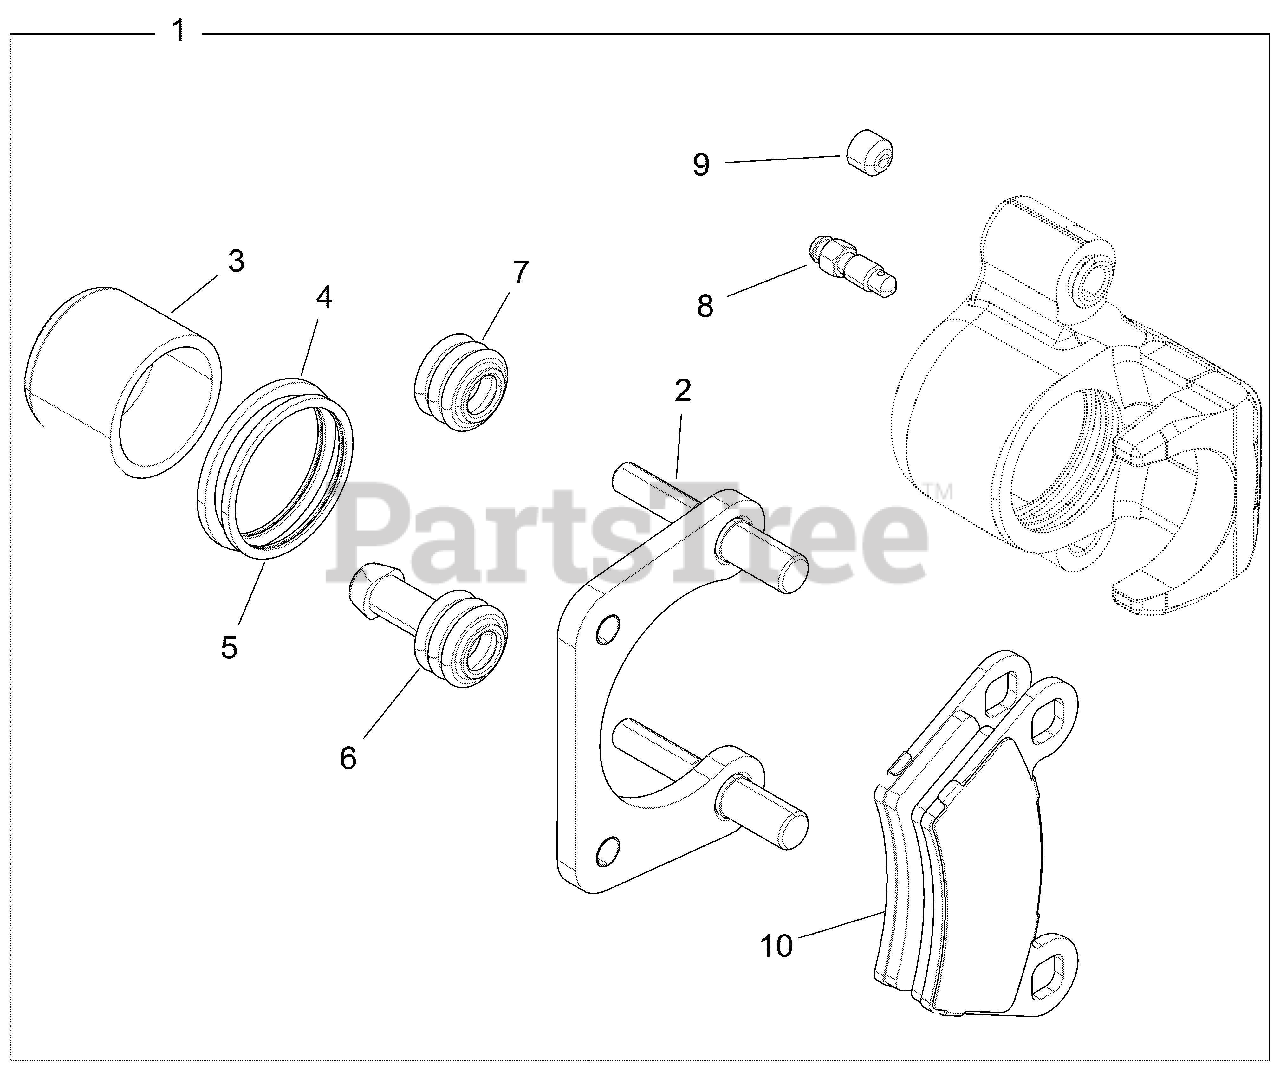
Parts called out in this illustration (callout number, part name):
1	ASM-CALIPER,BRAKE,1.5,LH,R MET
1	ASM-CALIPER,BRAKE,1.5,RH,R MET
2	ASM-CALIPER MOUNT,REAR,METRIC
3	PISTON-BRAKE,1.500
4	SEAL-CALIPER INNER,1.50"
5	SEAL-CALIPER,OUTER,1.50"
6	BOOT-PIN BUSHING
7	BOOT-PIN SEAL
8	SCR-M7X1.0,BLEEDER,OLIVE D
9	SCR-M10X1.0X8,SOC SET-OD
10	KIT-BRAKE PAD,ASM,1.5(INCL 4 P
